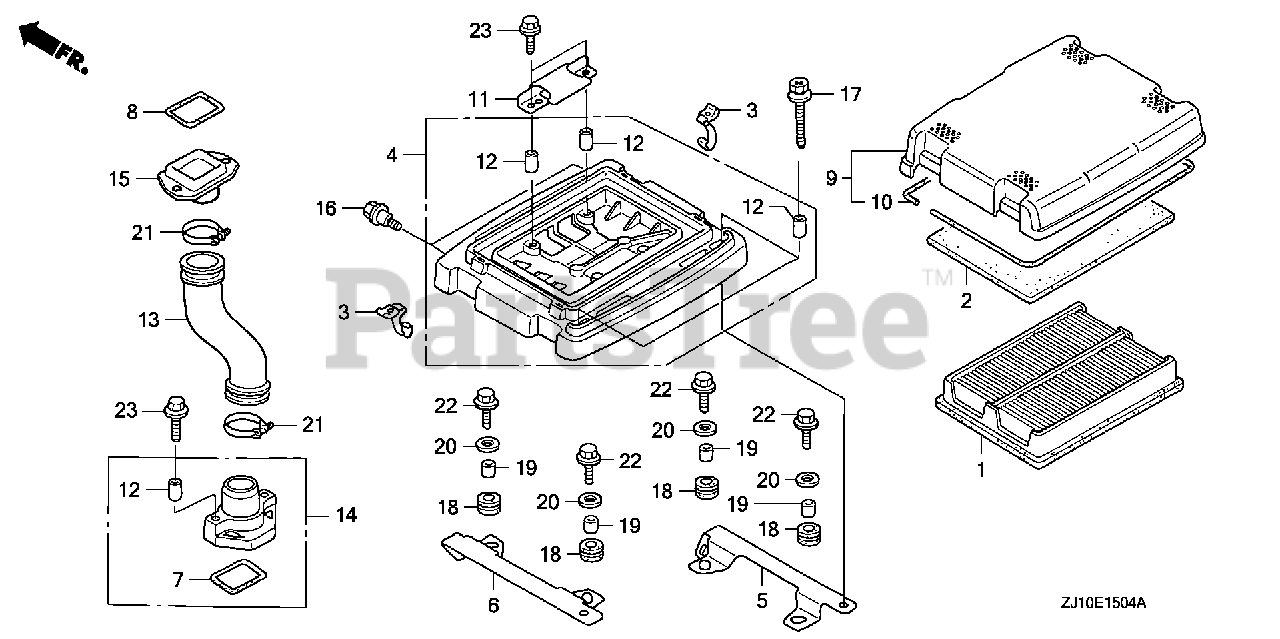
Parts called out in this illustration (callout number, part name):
1	ELEMENT, AIR CLEANER
2	FILTER (OUTER)
3	CLIP, AIR CLEANER
4	HOUSING, AIR CLEANER
5	STAY, R. AIR CLEANER HOUSING
6	STAY, L. AIR CLEANER HOUSING
7	SEAL, AIR CLEANER HOUSING
8	SEAL, AIR CLEANER HOUSING
9	COVER ASSY., AIR CLEANER
10	SEAL, AIR CLEANER COVER
11	PLATE, AIR CLEANER SETTING
12	COLLAR A, AIR CLEANER
13	TUBE, AIR CLEANER CONNECTING
14	JOINT ASSY., CONNECTING TUBE (B)
15	JOINT A, CONNECTING TUBE
16	BOLT, FLANGE (6MM)
17	BOLT-WASHER (5X30)
18	RUBBER, CONTROL BOX
19	COLLAR, CONTROL BOX
20	WASHER, PLAIN (6MM)
21	BAND, AIR CLEANER CONNECTING TUBE (58)
22	BOLT, FLANGE (6X20)
23	BOLT, FLANGE (6X28)
